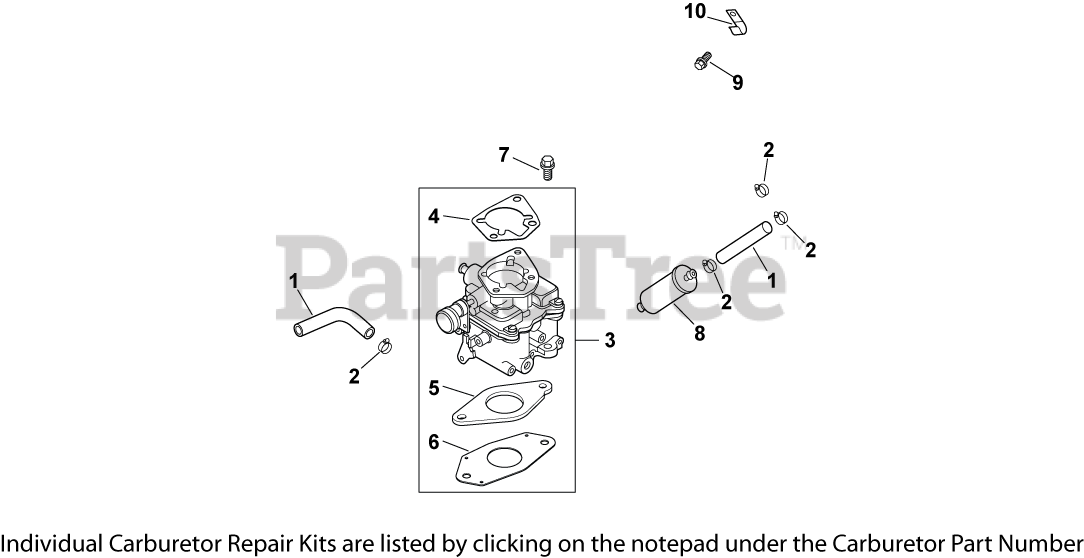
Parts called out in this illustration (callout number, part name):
1	HOSE,LW PERM.FUEL 24.00"-USE 25 111 81-S
2	CLAMP, HOSE (KM)-USE 25 237 31-S
3	KIT, CARBURETOR W/GASKETS USE 24 853 257-S
4	GASKET, AIR CLEANER BASE
5	GASKET, CARBURETOR
6	GASKET, CARBURETOR
7	SCREW, FLG M6X1.0X25
8	FILTER, FUEL
9	SCREW, FLNG THD FRM M6X1.0X10 USE 25 086 406-S
10	CLIP, CABLE - USE 24 154 10-S
